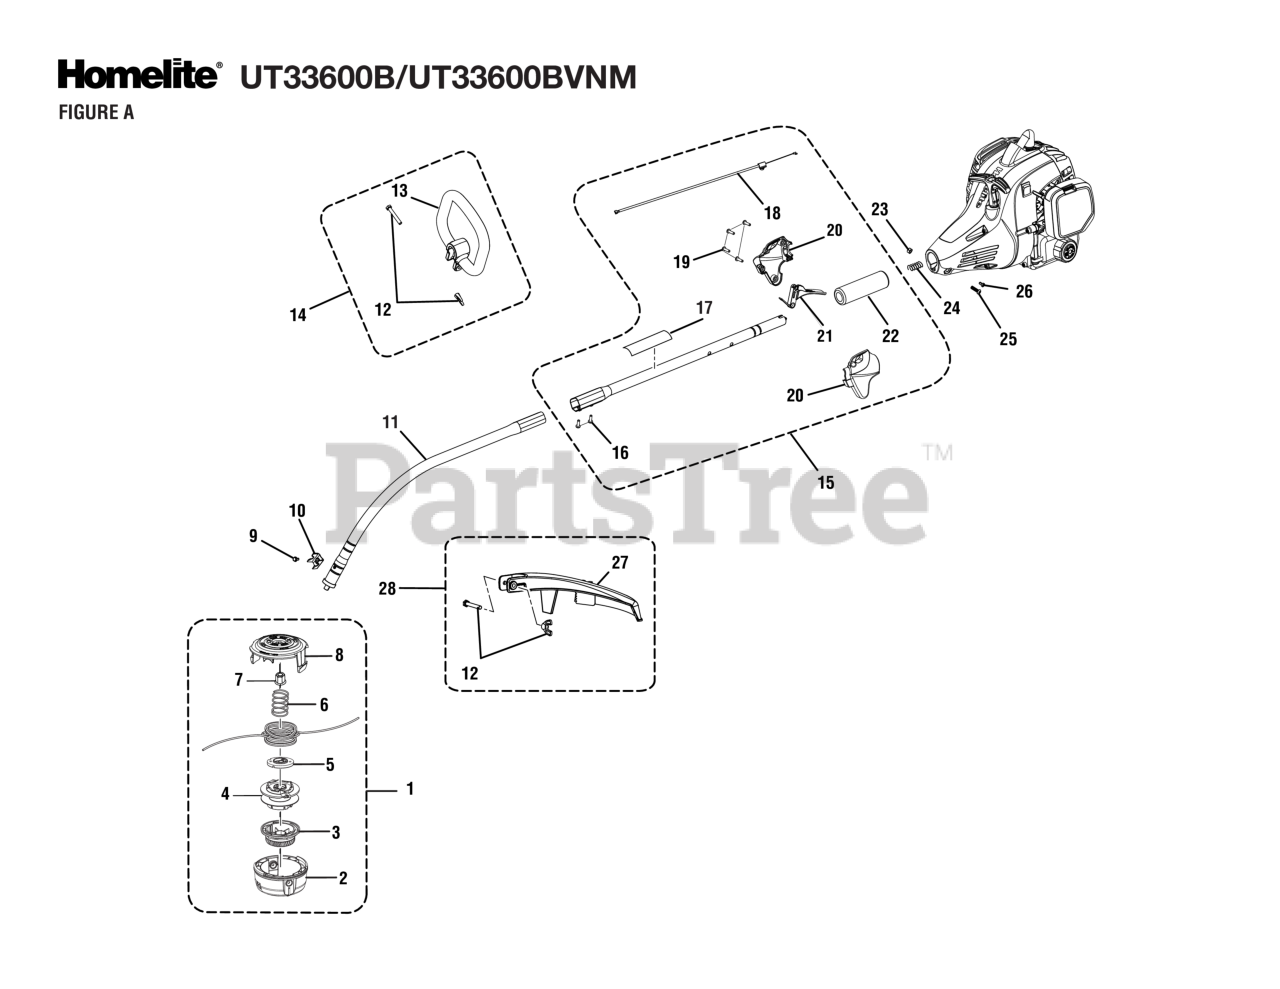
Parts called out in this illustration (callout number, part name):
1	Trimmer Head Assembly
2	Lower Housing
3	Bump Knob (Gray)
4	Spool Assembly
5	String Guide
6	Compression Spring
7	Flange Nut (M8)
8	Upper Housing
9	Screw (#10-32 x 3/8 in., Hex Washer Hd. S.T.)
11	Lower Boom Assembly
12	Fastener Parts Kit
13	Front Handle
14	Front Handle Assembly
15	Boom Assembly
16	Set Screw (M5 x 10 mm, Hex Soc. Hd.)
17	Icon Warning Label
18	Throttle Cable
19	Screw (M4 x 20 mm, T20 Torx Pan Hd. T.Fl.)
20	Trigger Handle Assembly
21	Throttle Trigger
22	Rubber Grip
23	Hex Nut (M6.3 x 1)
24	Compression Spring
25	Screw (M6 x 20 mm, T27 Torx Button Hd.)
26	Screw (M4 x 8 mm, T25 Torx Pan Hd. T.F.)
27	Grass Deflector
28	Grass Deflector Assembly
